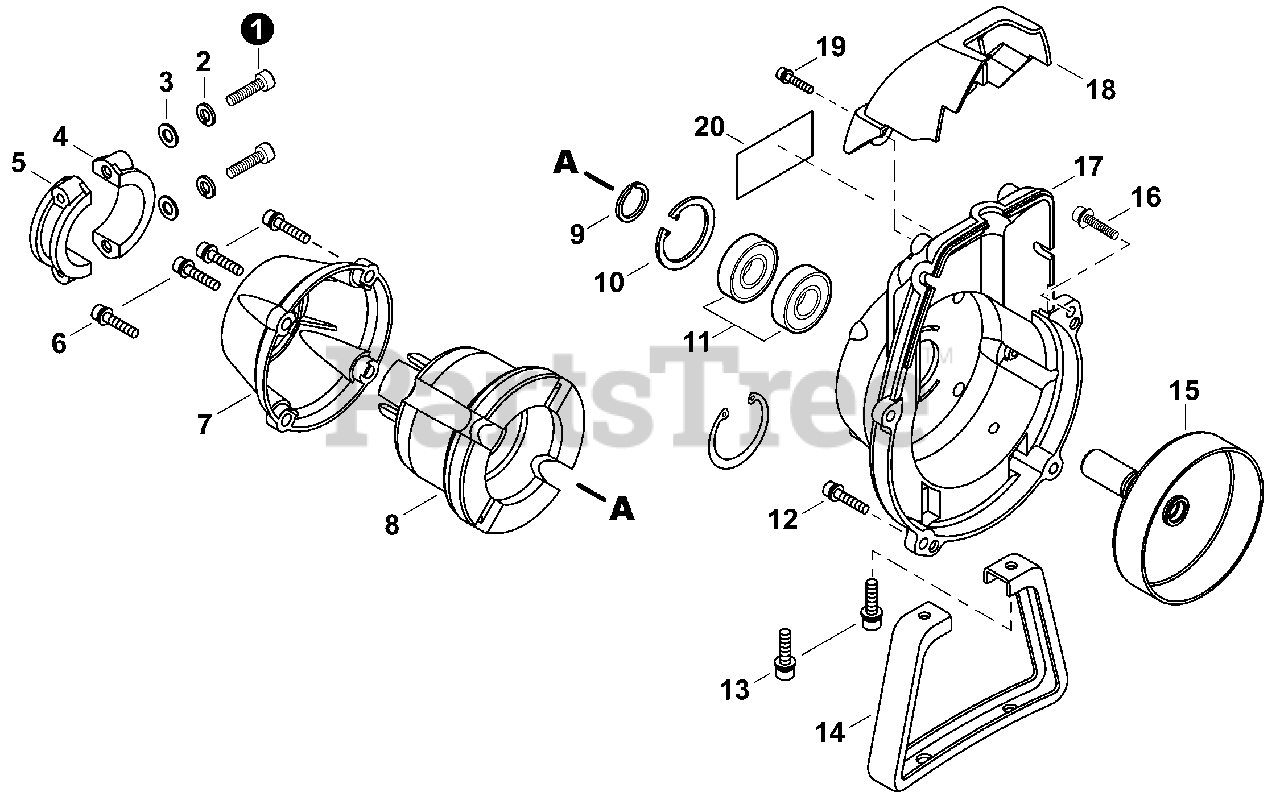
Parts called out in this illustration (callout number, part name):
1	BOLT 5×25
2	WASHER, SPRING 5
3	WASHER, FLAT 5.5×10×0.8
4	CLAMP (B)
5	CLAMP (A)
6	BOLT M5×20
7	CAP, CUSHION
8	CUSHION, AV
9	RING, SNAP
10	RING, SNAP Ø32
11	BEARING, BALL 6002 DDU
12	BOLT M5×20
13	BOLT M5×16
15	DRUM ASSY, CLUTCH
16	BOLT M5×30
17	COVER, FAN
18	GUARD, TOP
19	BOLT M4×16
20	LABEL - MODEL B45LA
